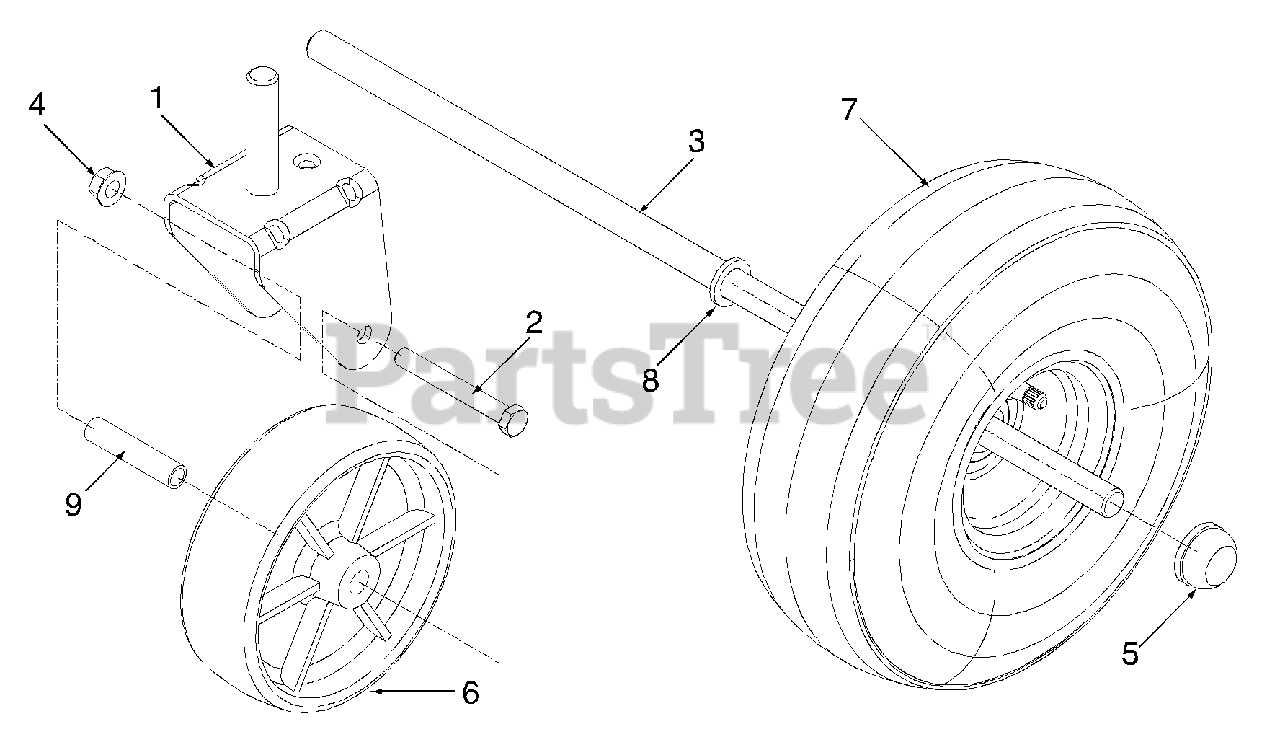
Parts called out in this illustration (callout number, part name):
1	Bracket Assembly, Pivot Wheel
2	Screw, Hex Cap, 3/8-16 x 3.0
3	Shaft, Rear Axle
4	Nut, Hex Flange Lock, 3/8-16
5	Push Cap
6	Wheel, 6.00 x 2.00
7	Wheel Assembly, Complete,10 x 4 x 4
8	Washer, Flat, .64 x 1.12 x .12
9	Spacer, .384 ID x .5 OD x 2.3 Lg
